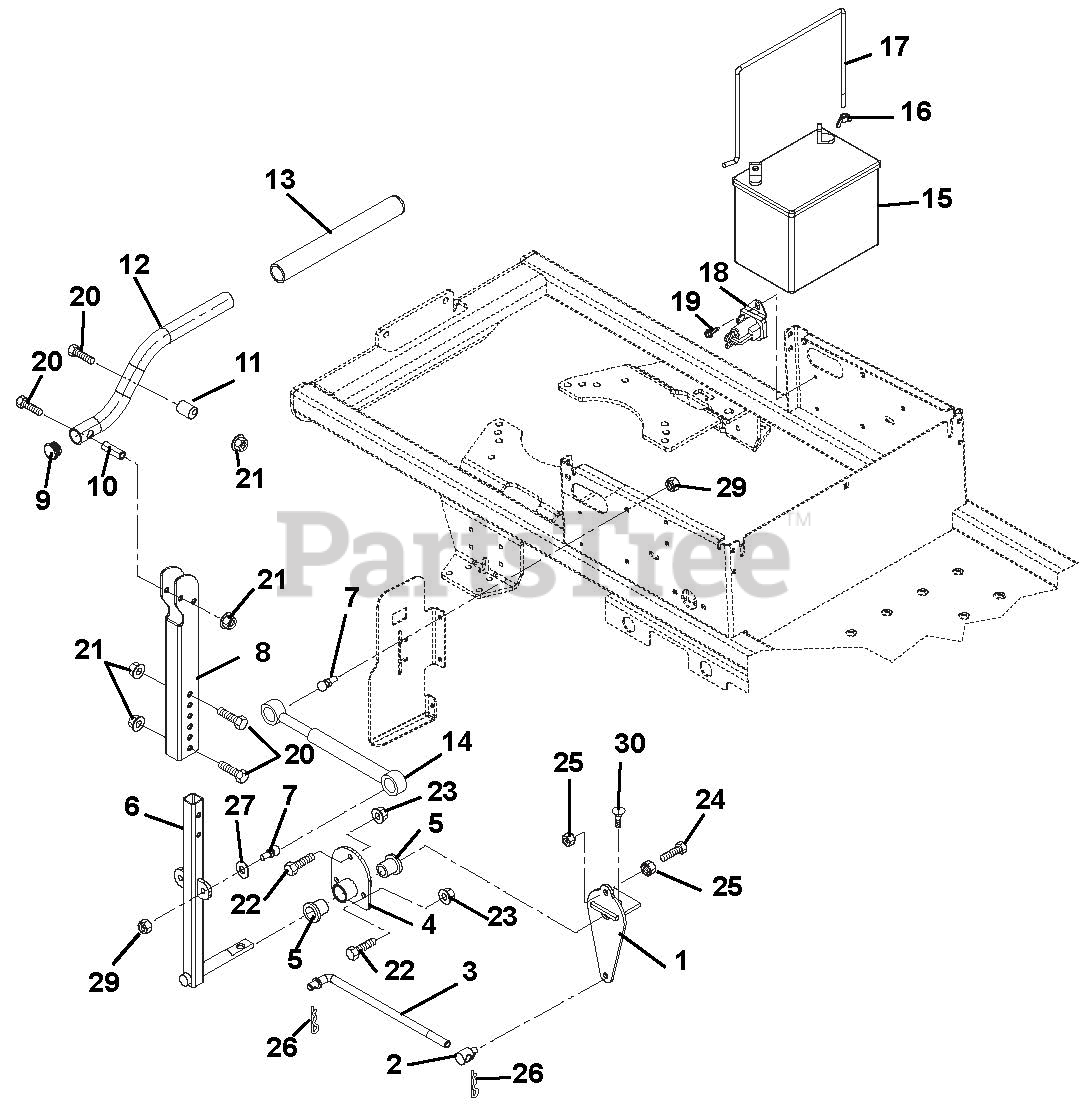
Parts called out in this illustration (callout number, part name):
1	CONTROL LINK WMT
2	PIVOT, ROD (TRUNNION ) .50
3	LINK,WIREFORM
4	WMT, STEERING BUSHING
5	BUSHING-1"X.75"X1"
6	WMT, CONTROL ARM
7	STUD- BALL
8	CHANNEL,UPPER HANDLEBAR
9	CAPLUG, HANDLEBAR
10	BSHG, SPCR .330X.500X1.01 PM
11	BSHG,ECCEN .328X.750X1.01 PM
12	HANDLE BAR
13	GRIP - HANDLEBAR
14	DAMPER, CONTROL
15	BATTERY, 300 CCA 10U1L
16	NUT-LK WING .250-20 YWZC
17	BATTERY ROD
18	SOLENOID
19	@SCR-TAP .25-20X.37 HWH YWZ TR
20	@BLT-HEX .31-18X1.75 GR5 YWZC
21	@NUT-LK-NYL-FLG .31-18 YWZC
22	@BLT-HEX .31-18X.75 GR5 YWZC
23	@NUT-LK-NYL-FLG .31-18 YWZC
24	BLT-HEX .38-16X3.00 GR5 FTH YZ
25	@NUT-SPNLK-FLG .375-16 YWZC
26	PIN-HAIR, ENDRIES #25 YWZC
27	@WSHR-LK .31X.078 REG YWZC
28	NUT- JAM .312-18 YWZC
29	@NUT-LK-TOP-FLG .31-18 YWZC
30	BOLT, 3/8-16X1 FSHCS PLN
